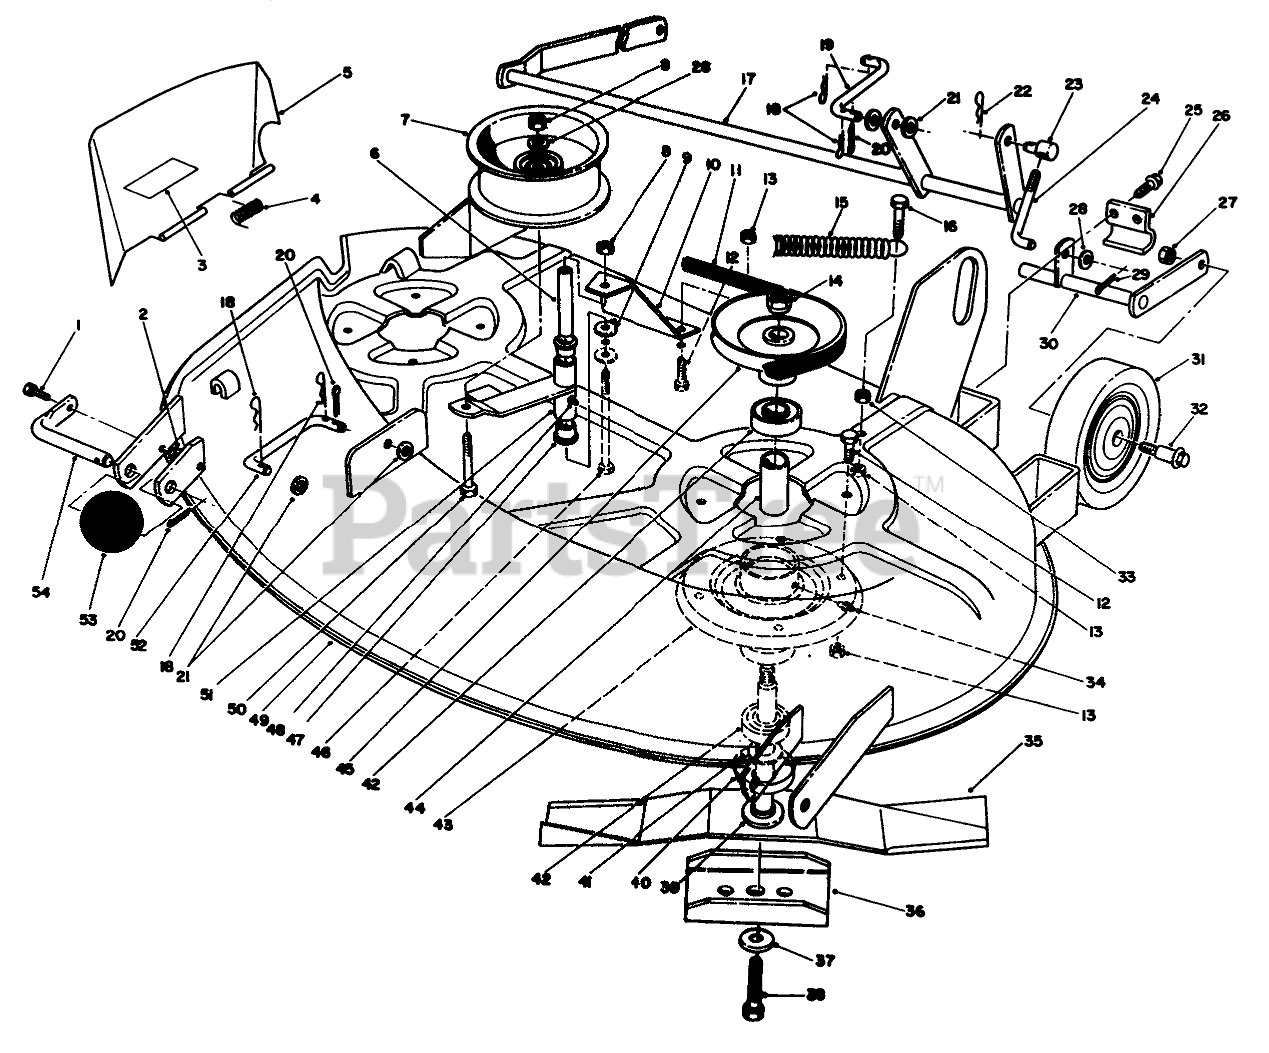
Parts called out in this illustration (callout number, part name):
1	SCREW-HH
2	NUT-LOCK, NI
3	DECAL-DANGER, THROWN OBJECT
4	SPRING-TORSION
5	Deflector
6	SPACER
7	Pulley-Idler
8	NUT-LOCK, NI
9	WASHER
10	Brace
11	V-BELT
12	SCREW-HH
13	NUT-LOCK, NI
14	Nut
15	SPRING-EXTENSION
16	SCREW-HH
17	Shaft-R.H.
18	PIN-COTTER
19	LINK-REAR
20	Cotter Pin
21	Washer
22	Hairpin
23	TRUNNION
24	ROD-LIFT
25	Bolt
26	Camp
27	Nut-Hex
28	WASHER-FLAT
29	PIN-COTTER
30	Shaft-L.H.
31	WHEEL
32	BOLT-SHOULDER
33	NUT-HEX
34	ZERK FITTING
35	BLADE KIT
36	Stiffener
37	WASHER-BELLEVILLE
38	SCREW-HH
39	SHAFT-SPINDLE
40	SHIELD-BEARING
41	SPACER-HARDNED
42	BEARING-BALL
43	Housing-Spindle
44	SPACER
45	Pulley-Spindle
46	SCREW-HH
47	BUSHING
48	FITTING-GREASE
49	Deck-Cutting Unit
50	SCREW-HH
51	Arm-Idler
52	LINK-FRONT
53	ROLLER
54	SHAFT-ROLLER
